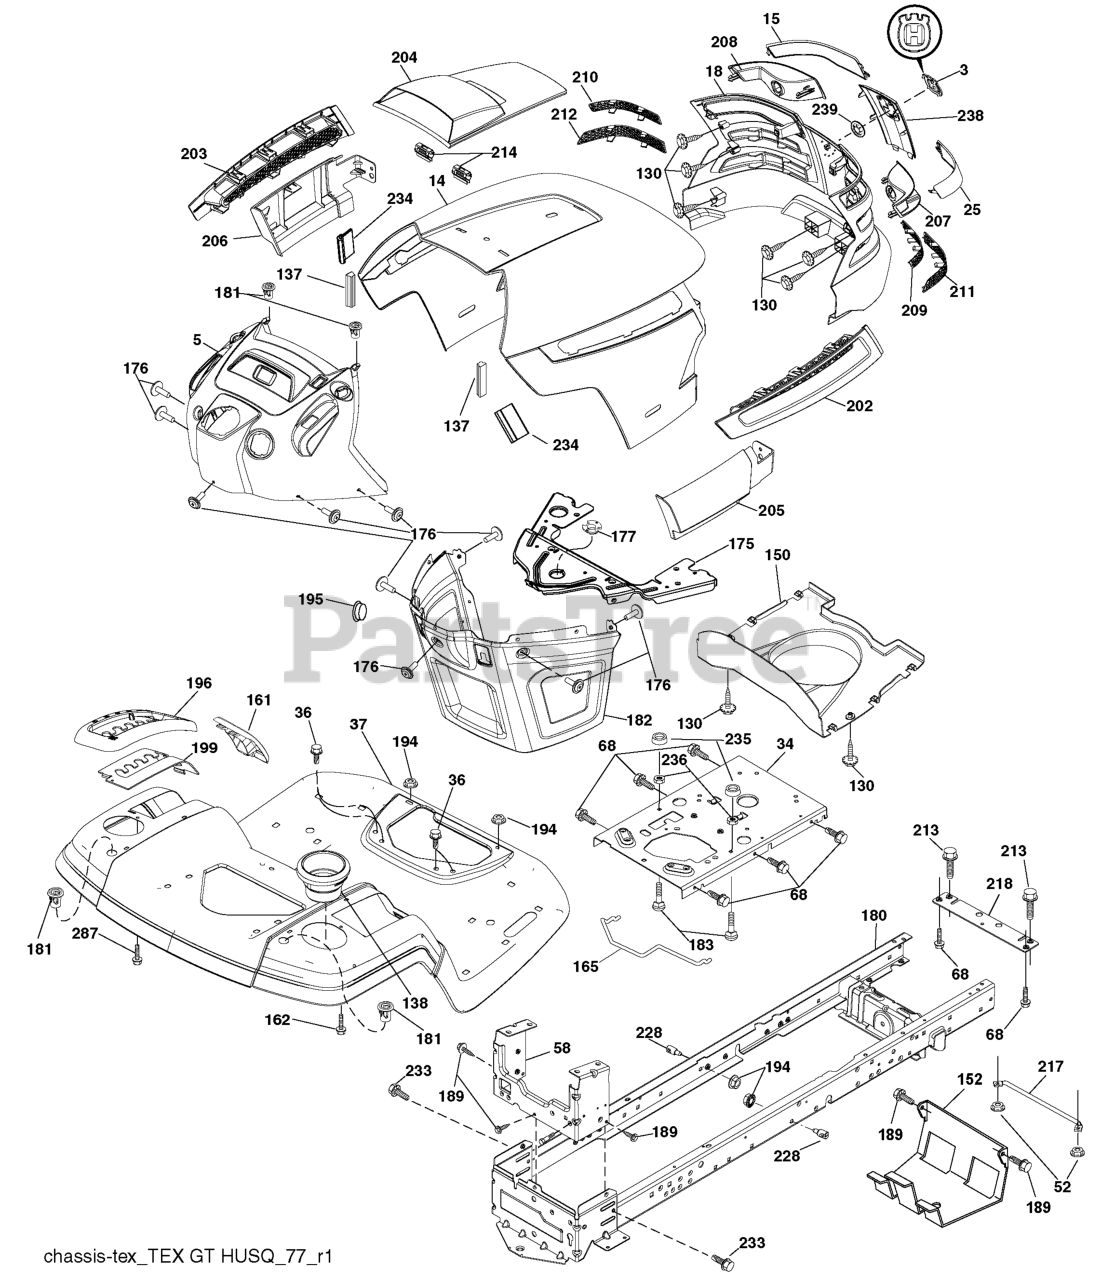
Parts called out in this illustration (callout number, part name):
3	RP LOGO
5	DASH.ASM.HUSQ.GT
14	HOOD
15	LENS.LH.TEX.GT.HUSQ.CL
18	GRILL.ASM.HUSQ.TG/CRD.W/TRIM
25	LENS.RH.TEX.GT.HUSQ.CL
34	PLATE.ENGINE.WELDED.CHASSIS
36	SCREW 5/16"
37	FENDER.TLT.W/CPH.W/FW.ORANGE
52	LOCKNUT
58	DRAWBAR UPPER 2PC SMALL FENDER
68	Screw 5/16-18 x 1/2
130	SCREW.#10 X 0.750.BOS
137	BUMPER DASH
138	CUPHOLDER.TL.TEX.418
150	AIR.DUCT.HOOD.TEX.GT.HUSQ
152	SHIELD.BROWNING.W/TEX
161	WINDOW FUEL
162	SCREW.HI-LO.CONSOLE
165	SUPPORT.TANK.REAR.W/TEX
175	PLATE.CROSSMEMBER.HUSQ
176	SCREW.#10-24X5/8.RN.QU
177	BUSHING, STEERING
180	CHASS.WLDMNT.TL.12GA/2P.48/54
181	BUSHING.MNT.FEND.CRGO.
182	DASH.LOWER.COMMON.12V.ADAPTOR
183	BOLT.5/16-18X1-1/4 FULL THD
189	SCREW
194	NUT LOCK HEX FLANGE 5/16-18
195	PLUG.HOLE.DASH.LOWER.12V.BLK
196	RP CONSOLE.ASM.DECKLFT.GR/RBT.
199	PLATE.DECK.LIFT.HUSQ.LT
202	VENT.SIDE.HOOD.HUSQ.RH.GREY
203	VENT.SIDE.HOOD.HUSQ.LH.GRAY
204	HOOD VENT
205	SKIRT.HOOD.SIDE.HUSQ.RH.GREY
206	SKIRT.HOOD.SIDE.HUSQ.LH.GREY
207	BEZEL.RH.TEX.GT.HUSQ
208	BEZEL.LH.TEX.GT.HUSQ
209	INSERT.HEX.GRILL.HUSQ.GREY
210	INSERT.HEX.GRILL.HUSQ.
211	INSERT.HEX.GRILL.HUSQ.
212	INSERT.HEX.GRILL.HUSQ.
213	BOLT
214	CLIP.RETAINER.TINNER.
217	ROD.PIVOT.HOOD
218	X-PIECE.HOOD.STOP.NON/
228	STUD.FASTNER.W/ANTI-ROTATE
233	BOLT.SHOULDER
234	BUMPER.HOOD.TEX.HUSQVARNA
235	SPACER FENDER
236	NUT.CENTERLOCK.5/16-
238	TRIM.HUSQ.TG/CRD.SERVICE
239	NUT PUSH M
287	SCREW 1/4X20
